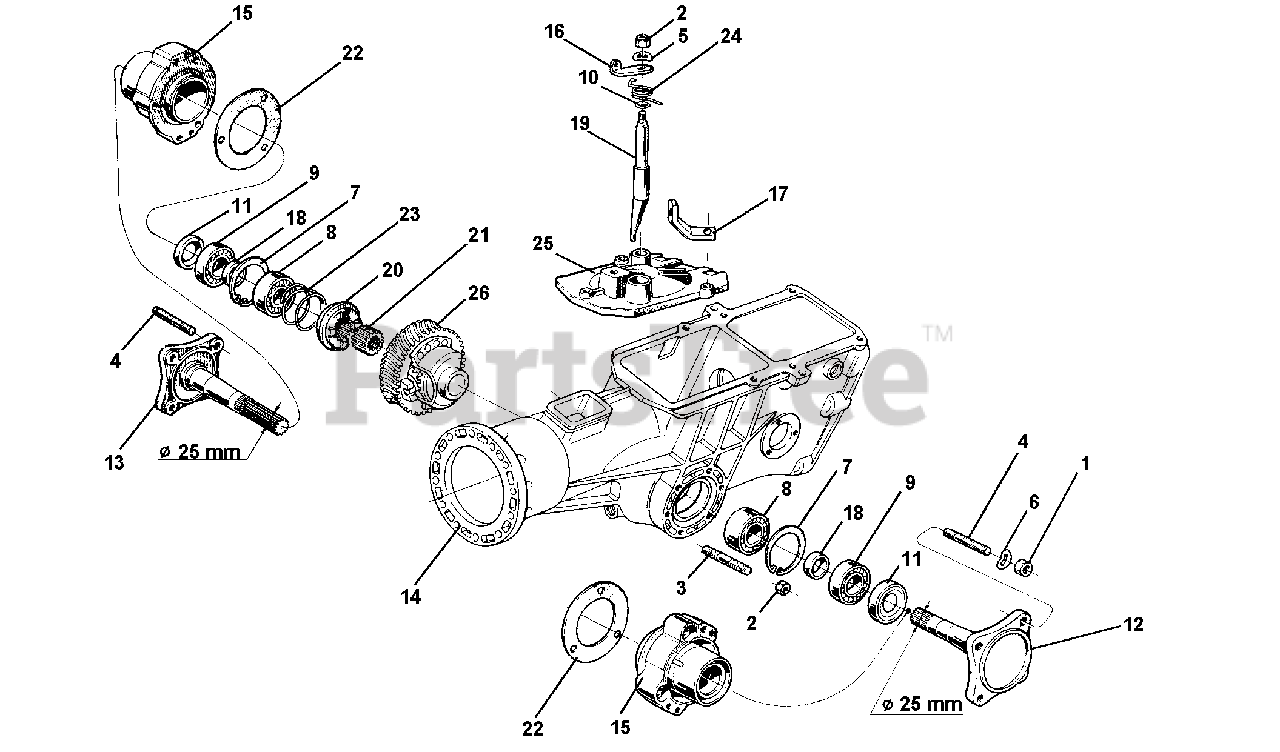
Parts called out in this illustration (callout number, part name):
2	NUT, SELF LOCKING M8
3	STUD M8 X 46 X 20 X 12
4	STUD M10 X 40 X 22 X 14
5	WASHER, FLAT 8.4
6	WASHER, LOCK 10.5
7	CIRCLIP, INTERN. D 47
8	BEARING 25 X 52 X 15 6205
9	BEARING 25 X 47 X 12
10	O-RING 2056 14.00 X 1.78
11	SEAL, OIL 30 X 40 X 7 STANDARD
12	SHORT HALF AXLE
13	LONG HALF AXLE
14	GEARBOX 745/606-605
15	HUB FOR HALF AXLE
16	LEVER RELEASE
17	CONTRAST DIFFERENTIAL SHEATH
18	HALF AXLE RING
20	FRONT COUPLING
21	TOOTHED SPACER
22	JOINT GASKET
25	COVER DIFFERENTIAL
26	DIFFERENTIAL 737
